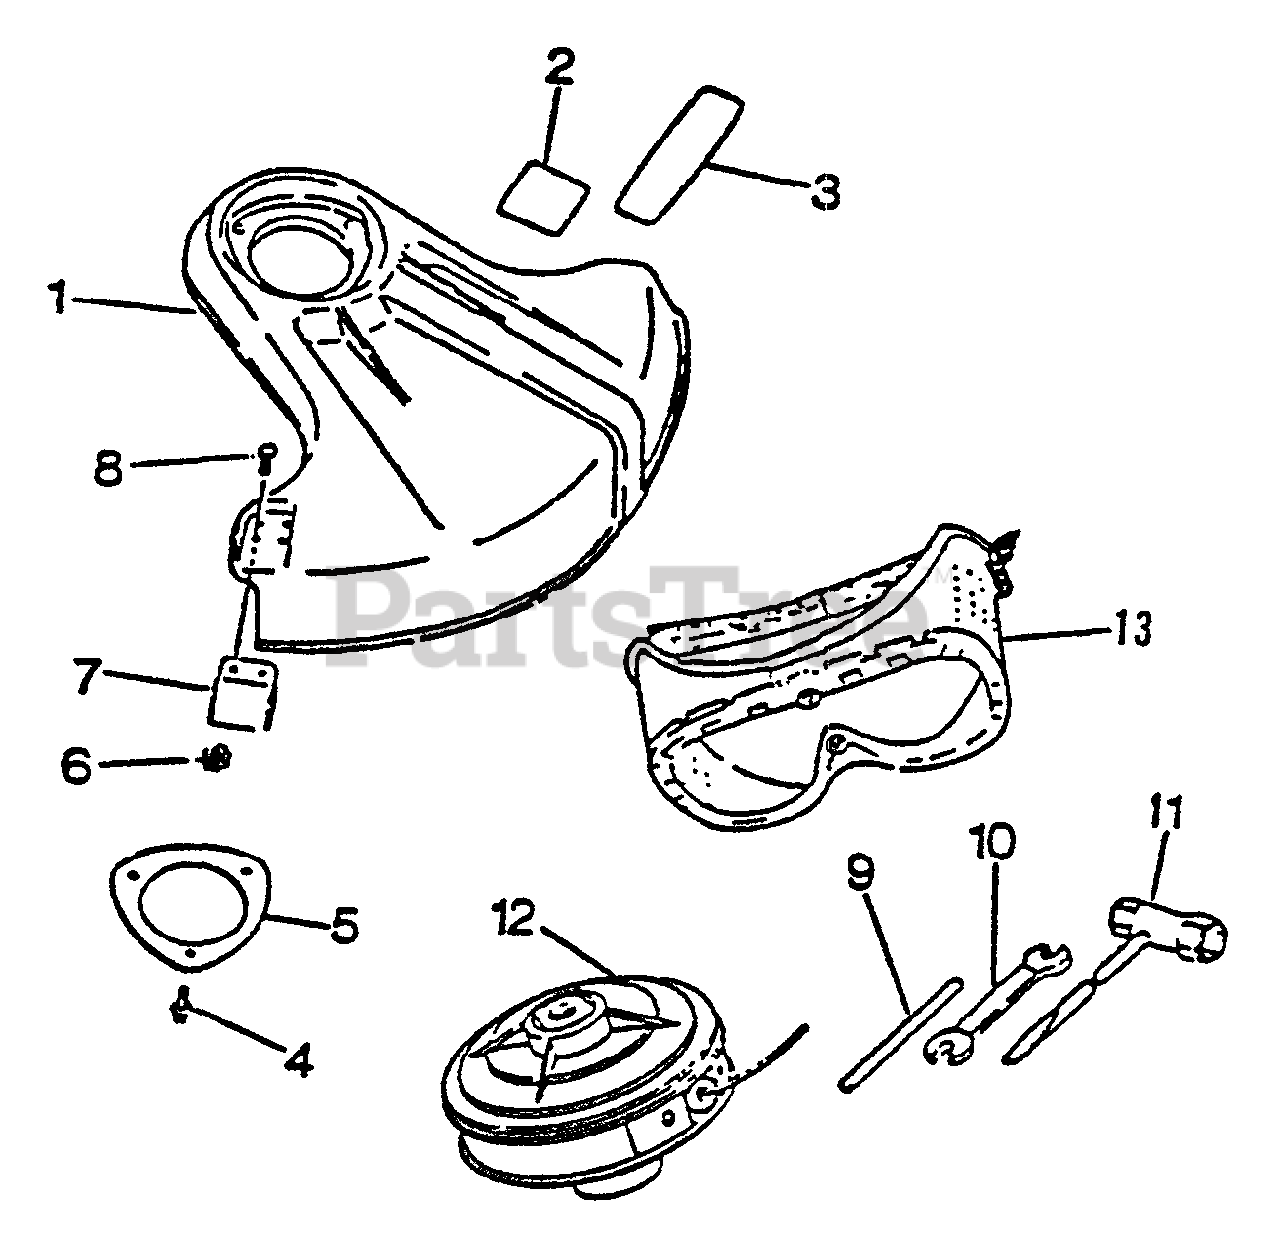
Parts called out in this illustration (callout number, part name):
1	SHIELD
2	LABEL, CAUTION
3	LABEL - ECHO
4	SCREW 5×16
5	PLATE, SHIELD Ø49.5 MM
6	NUT, HEX M6
7	CUTTER, LINE
8	SCREW 5×16
9	TOOL, LOCKING 5×120 MM
10	SPANNER 8×10
11	T-WRENCH 17x-19 L200
12	TRIMMER HEAD, SRM ECHOMATIC®
13	GOGGLES
